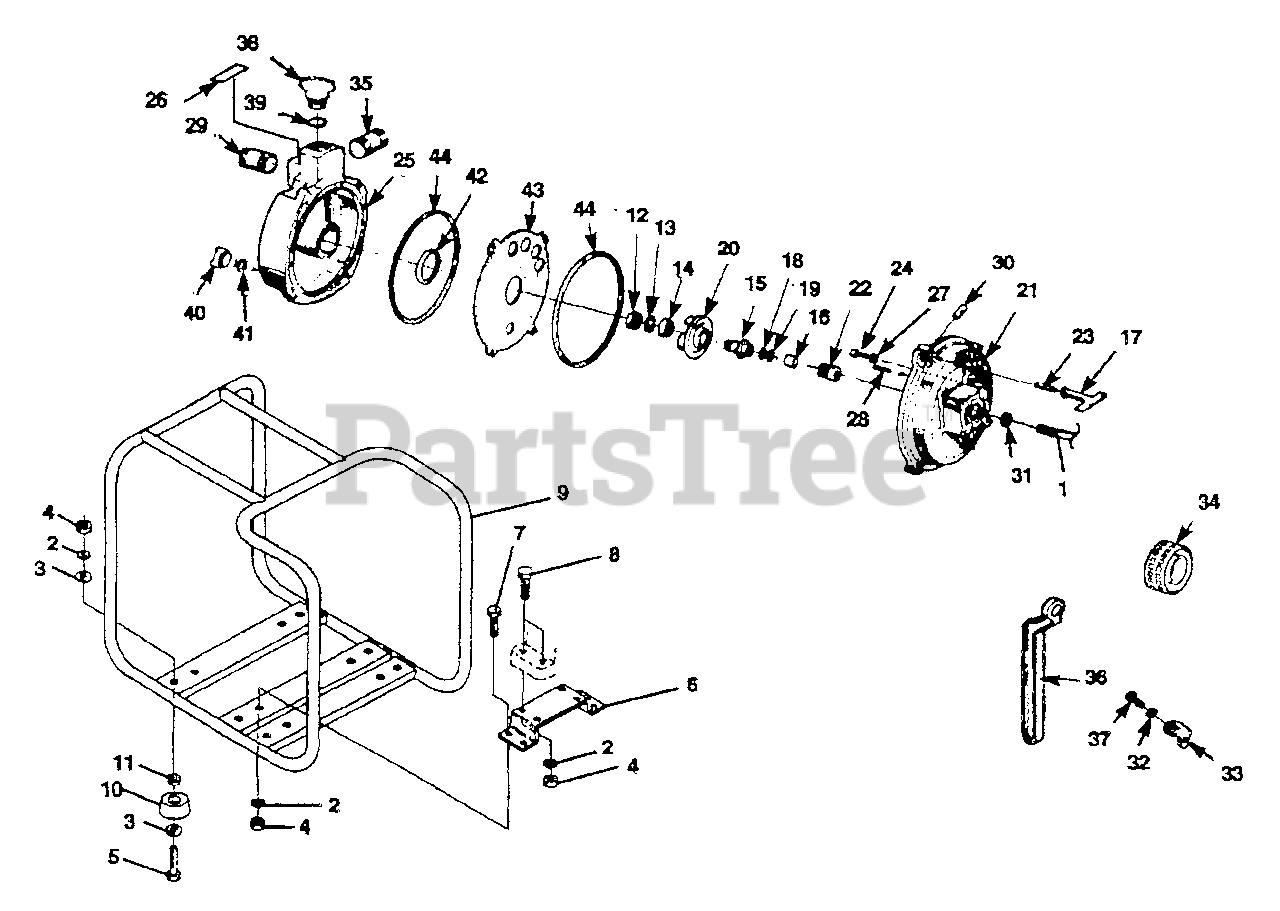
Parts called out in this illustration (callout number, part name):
1	ENGINE
2	WASHER - Lock (5/16)
3	WASHER - Flat (5/16)
4	NUT - Hex (5/16-18)
5	SCREW - Hex hd (5/16-18 x 1.25)
6	ENGINE - Support
7	SCREW - Hex hd (5/16-18 x 1.00)
8	SCREW - Cap hex hd. (5/16-18 X 1 1/2")
9	ROLL CAGE
10	RUBBER FOOT
11	FOOT SPACER
12	NUT - Impeller
14	BUSHING - Impeller
15	HUB - Impeller
16	SPACER - Crankshaft
17	HANDLE - Disconnect
18	SHIM - (.010")
19	SHIM - (.015")
20	IMPELLER-Pump
21	HOUSING - Impeller
22	SEAL - Shaft
23	STUD - Handle
24	SCREW - Mach. hex hd (5/16-24 x 2 1/4")
25	HOUSING - End
26	DECAL - Fill pump
27	WASHER - Sealing
28	PIN - Coiled spring
29	NIPPLE - (2" x 2")
30	PIVOT- Handle
31	SLINGER
32	WASHER - Flat (1/4")
33	HOLDER - Spanner wrench
34	STRAINER - Suction hose
35	NIPPLE - (2" x 3 1/2")
36	WRENCH
37	SCREW - Cap hex hd.
38	PLUG - Wing
40	PLUG - Drain
42	GASKET - Small
43	PLATE - Wear
44	GASKET - Large
